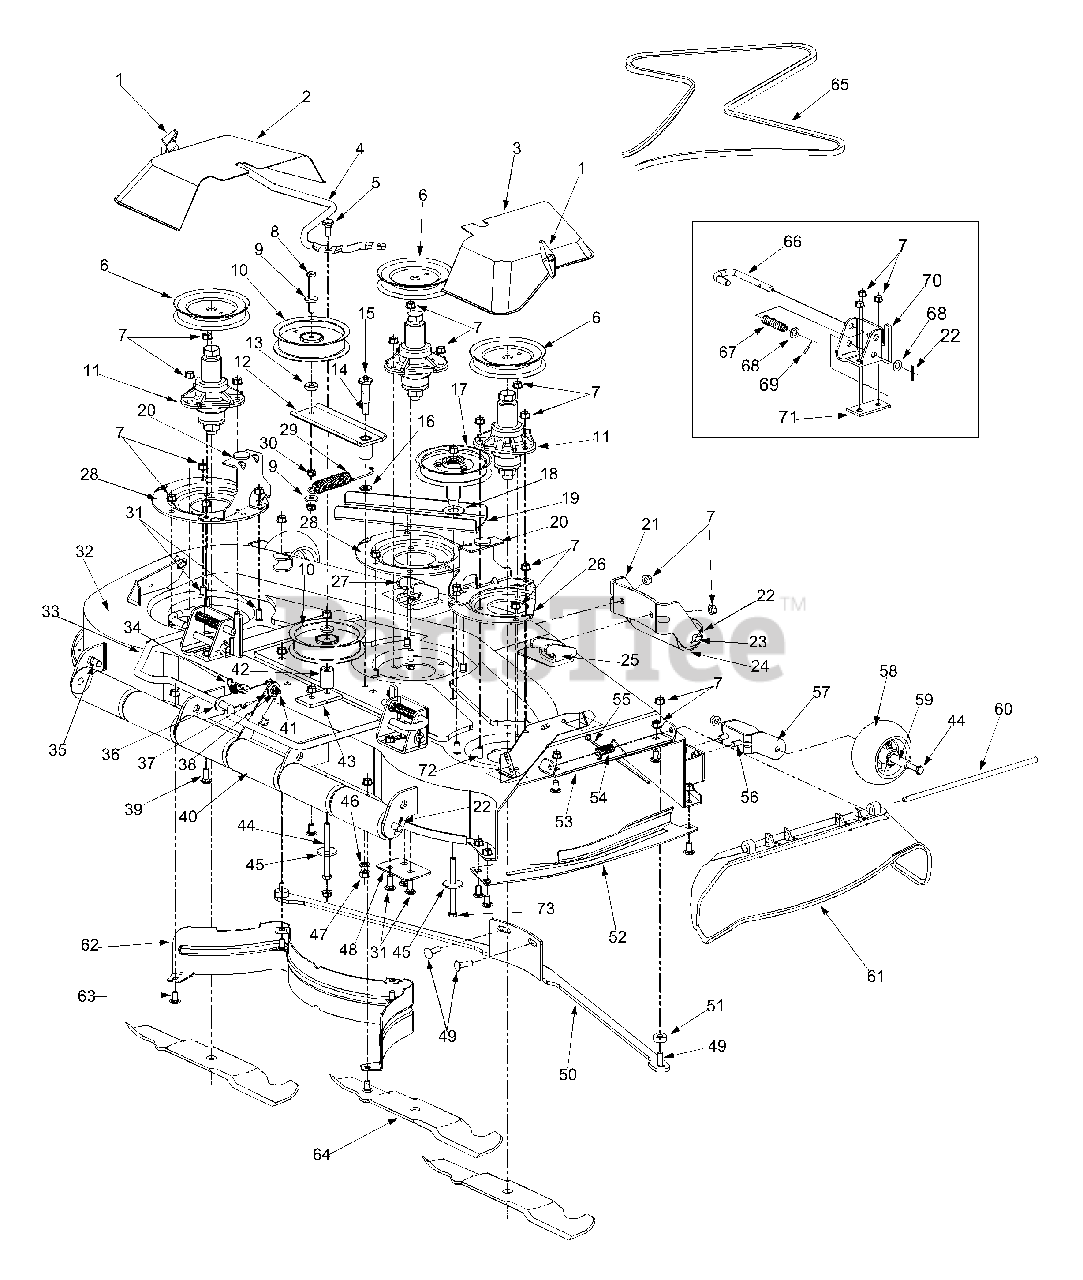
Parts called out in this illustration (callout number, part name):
1	Wing Nut Knob
5	Shoulder Screw 3/8-16
6	Pulley
7	Flange Lock Nut 3/8-16
8	Hex Cap Screw 3/8-16 x 3.0
9	Flat Washer .385 ID x 1.0 OD
10	Idler Pulley 5.0
11	Deck Spindle Ass'y
14	Shoulder Bolt
15	Grease Fitting
16	Flat Washer .469 ID x .875 OD
17	Idler Pulley Ass'y 5.0
18	Flat Washer .78 ID x 1.59 OD
23	Roller Pin
30	Lock Nut 3/8-16
31	Carriage Bolt 3/8-16
34	Extension Spring .50 OD x 2.51 Lg
38	Flange Lock Nut 5/16-18
39	Carriage Bolt 3/8-16
41	Shoulder Screw
46	Lock Washer 7/16
47	Hex Nut 7/16-14
54	Torsion Spring
56	Hex Cap Screw 3/8-16 x .880
61	Deflector Chute
63	Carriage Bolt 3/8 - 16
64	Blade
65	Belt
67	Compression Spring
68	Flat Washer .536 ID x .93 OD
73	Hex Cap Screw 3/8-16 x 4.5
